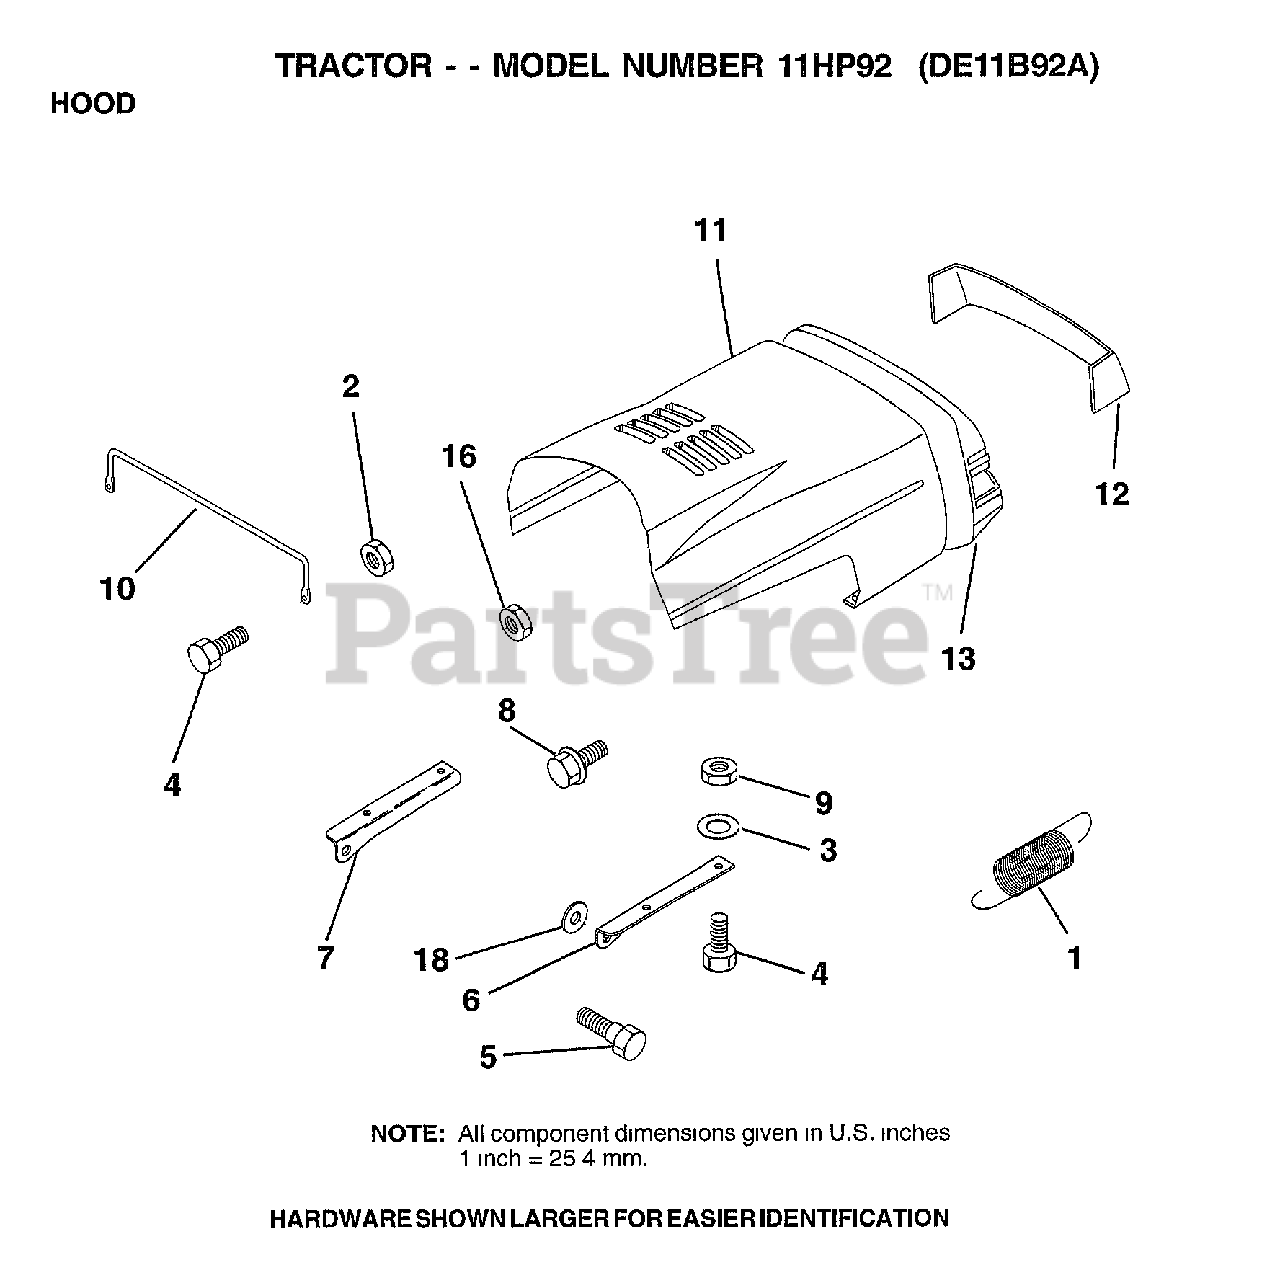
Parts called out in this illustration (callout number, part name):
1	EXT SPRING
2	NUT
3	WASHER
5	BOLT.SHLD.5/16-18
6	BRKT HOOD RH
7	BRKT HOOD LH
8	"SCREW,HWHD.HI-LO#13-16X3/4"
9	NUT
10	"BRACE,HOOD"
12	LENS.LR.JET.GRAY
13	GRILLE.LR.BLACK
16	NUT
18	WASHER
